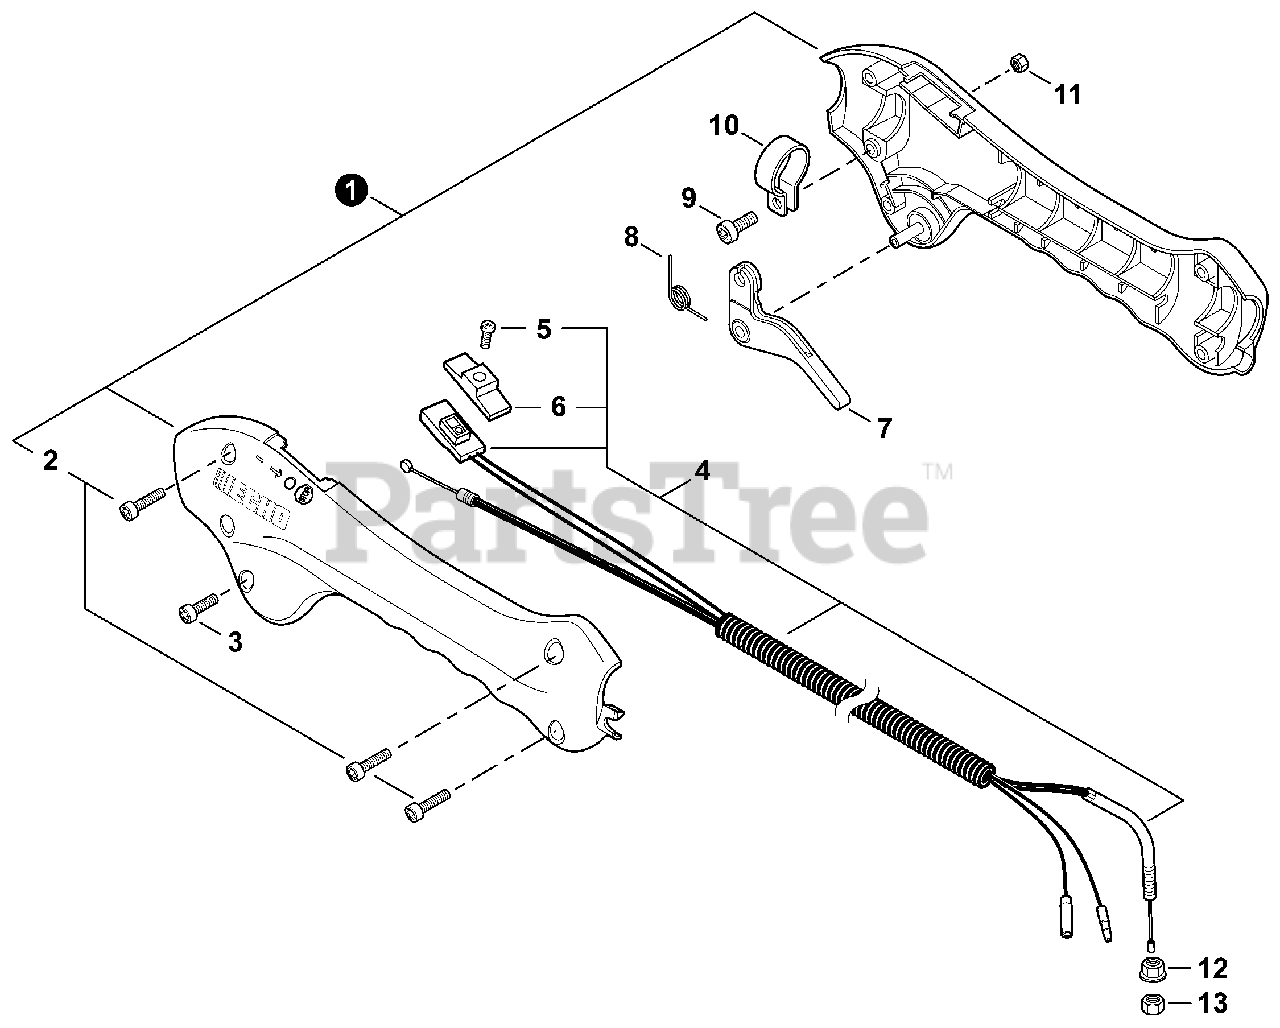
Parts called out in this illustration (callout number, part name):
1	CONTROL HANDLE KIT
2	BOLT, TORX 4×16
3	BOLT, TORX 4×12
4	CABLE ASSY, CONTROL
5	SCREW 3×10
6	KNOB, SWITCH - ORANGE
7	TRIGGER, THROTTLE
8	SPRING, TORSION
9	BOLT, TORX 5×12
12	NUT, FLANGE M6
